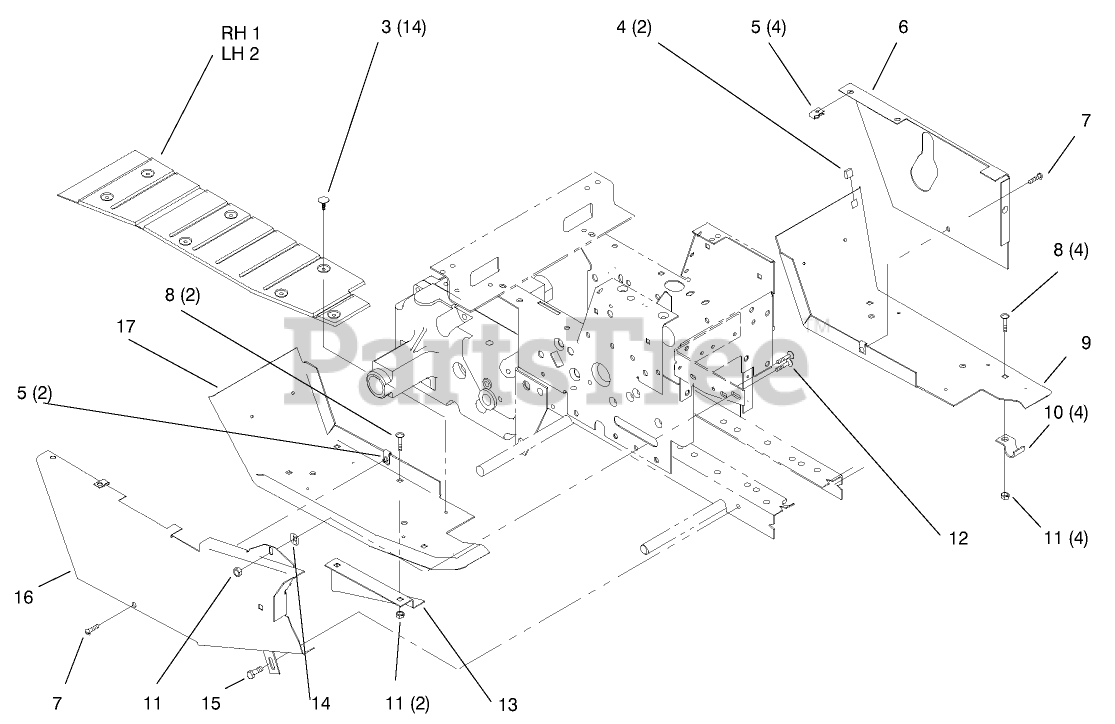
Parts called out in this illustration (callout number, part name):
2	PAD-FOOT LH
3	FASTENER-PANEL
4	BUMPER
7	SCREW-PPH
8	BOLT-CARR
10	BRACKET
11	NUT-LOCK, NI
12	BOLT-CARR
